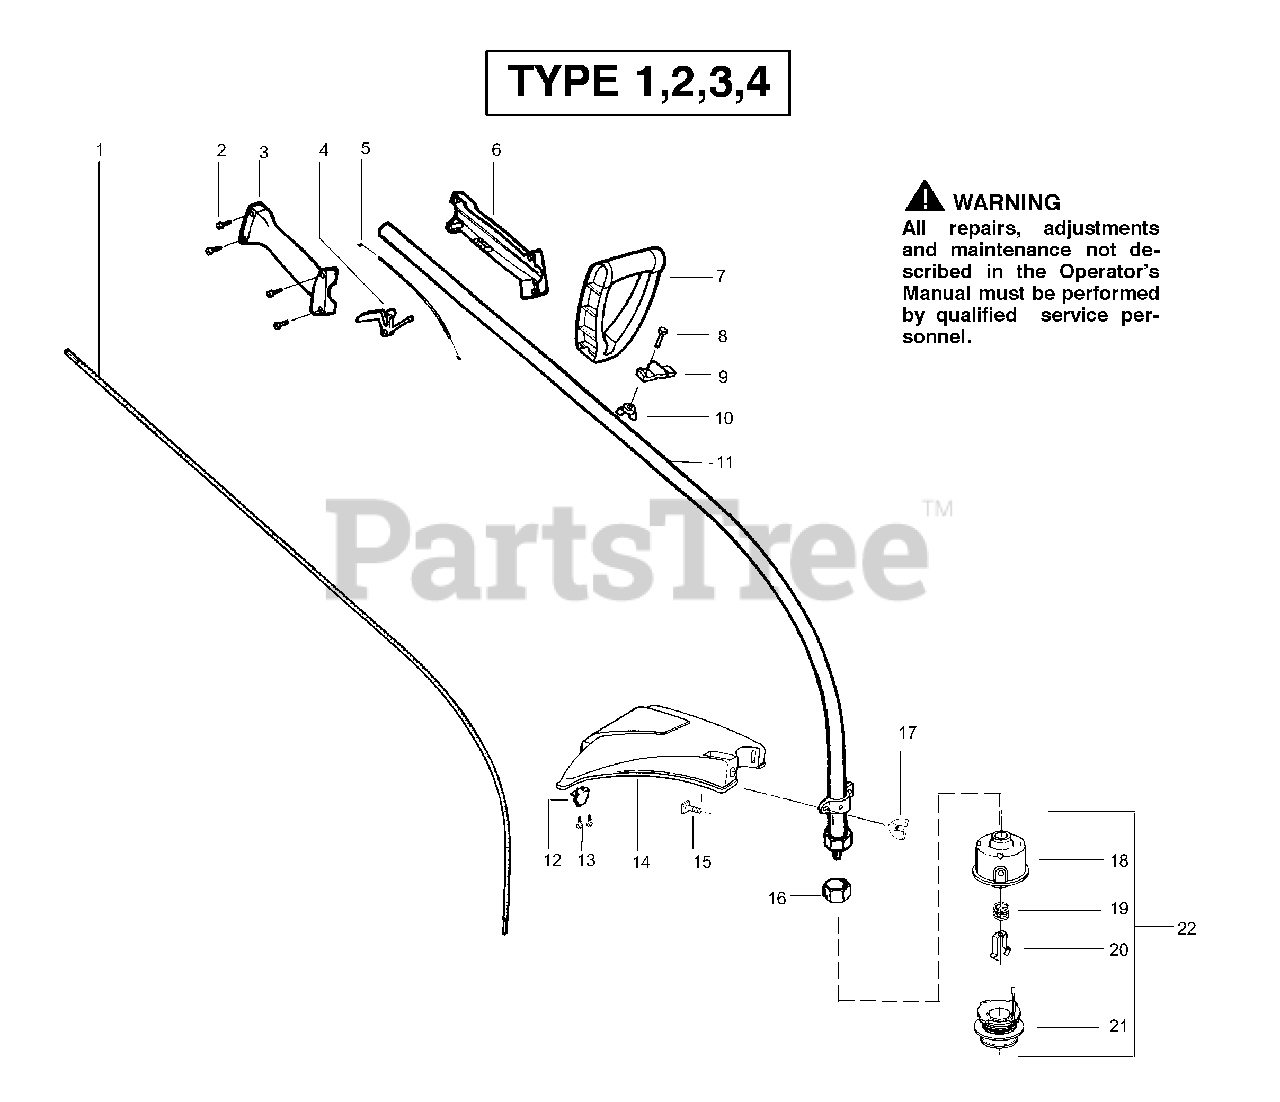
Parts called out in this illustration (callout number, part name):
1	Shaft-Flex (type 1,2)
1	Shaft-Flex (type 3,4)
2	Screw-Throttle Hsg.
3	Throttle Hsg. (Right)
5	Assy-Throttle Cable (type 1)
5	Assy-Throttle Cable (type 2,3,4)
6	Throttle Hsg. (Left) (type 1,2)
6	Throttle Hsg. (Left) (type 3,4)
7	Assist Handle
8	Bolt-Handle/Shield
9	Clamp-Assist Handle
10	Wingnut
11	Assy-Drive Shaft Hsg. (type 1,2)
11	Assy-Drive Shaft Hsg. (type 3,4)
12	Line Limiter
13	Screw-Line Limiter
14	Kit-Shield Ass'y.
15	Bolt-Handle/Shield
16	Dust Cup
17	Wingnut
18	Hub Ass'y.
20	Clip-Retainer-Head
21	Spool w/Line
22	Accy-Cutting Head Assy
